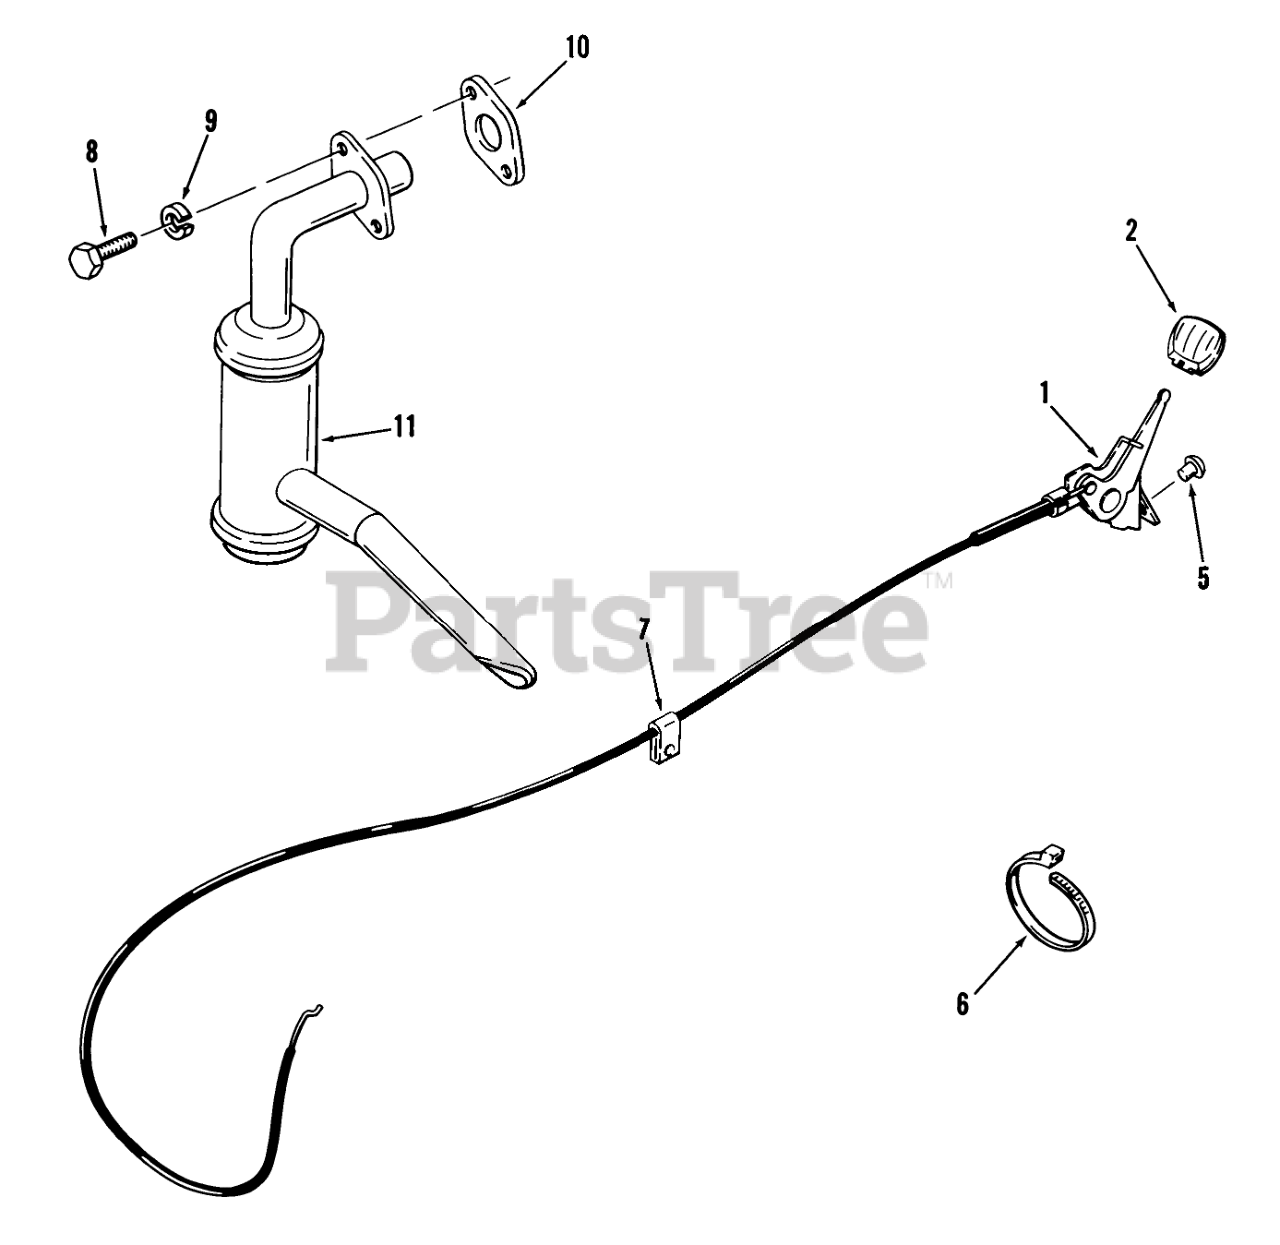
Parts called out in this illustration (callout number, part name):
1	CHOKE & THROTTLE CON
2	KNOB-THROTTLE
5	Pip Rivet
6	PLASTIC TIE
7	THROTTLE CONTROL CLP
8	Bolt
9	Lockwasher
10	Gasket Exhaust
11	Muffler
